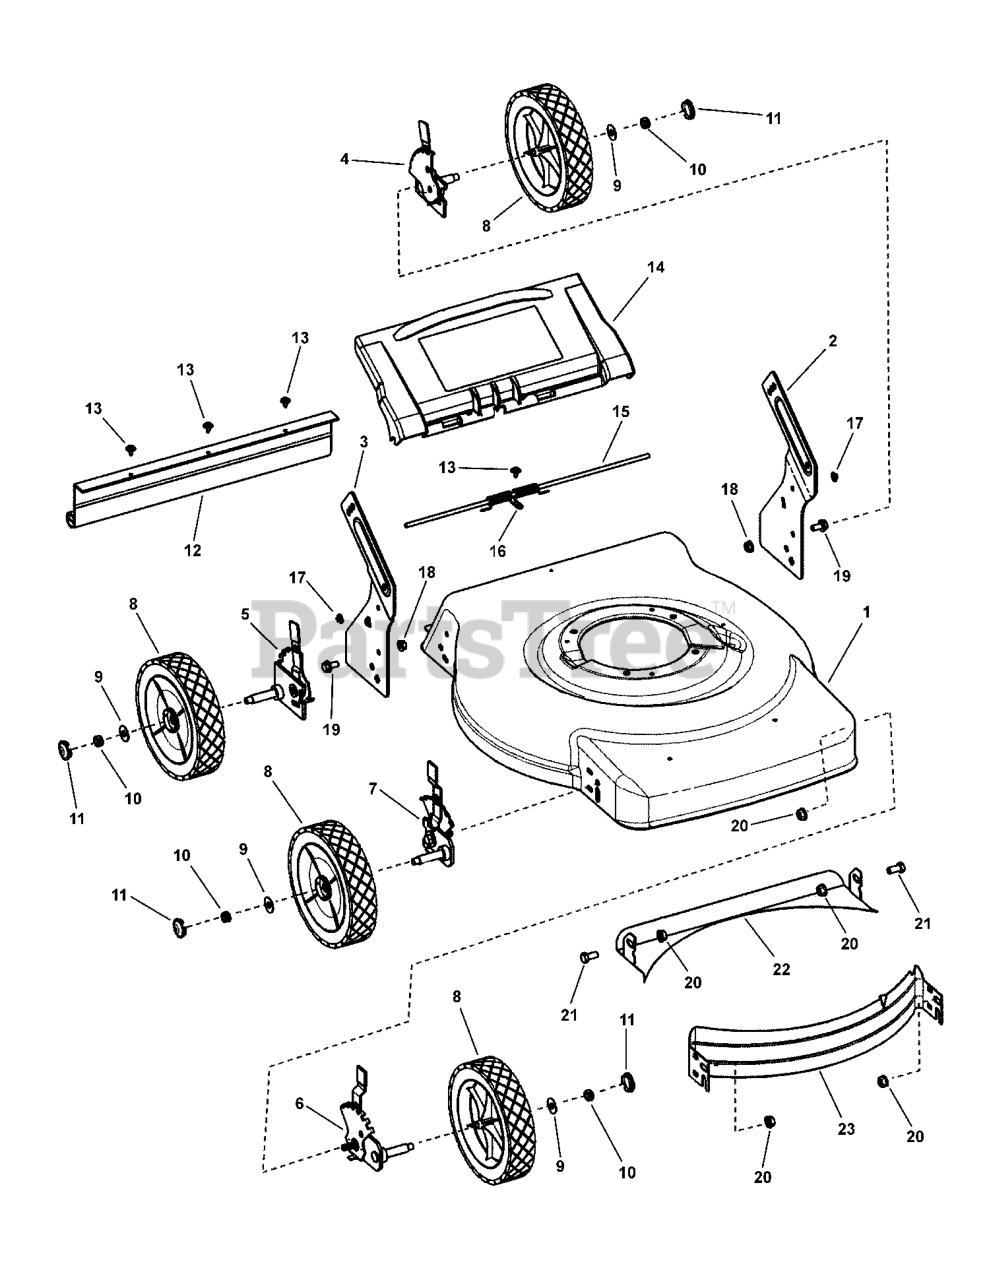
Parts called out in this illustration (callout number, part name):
1	DECK, 22 Walk-Behind
2	BRACKET, Lower Handle, 22 WBM, LH
3	BRACKET, Lower Handle, 22 WBM, RH
4	ASSEMBLY, Height-of-Cut, Right Rear
5	ASSEMBLY, Height-of-Cut, Left Rear
6	ASSEMBLY, Height-of-Cut, Left Front
7	ASSEMBLY, Height-of-Cut, Right Front
8	WHEEL, 8 x 2 Diamond-Pewter
9	WASHER, .382 ID x 1" OD x .031 Flat
10	NUT, 3/8-16 Hex Center Lock, YZ
11	HUBCAP, P290-Black
12	GUARD, Rear, 22 Deck Mower
13	SCREW, #10-24 x 1/2" Hex Washer Self-Tap (Sems)
14	DOOR, Rear, 22"
15	ROD, Pivot, Rear Door
16	SPRING, Torsion, Rear Door, 22 Walk
17	PUSHNUT, 1/4"
18	NUT, 5/16-18 Large Flange Center Lock
19	BOLT, 5/16-18 Hex Flange Lock
20	NUT, 3/8-16 Hex Flange Lock, GR 5
21	SCREW, 3/8-16 x 3/4", Hex Head Cap, GR 5
22	BAFFLE, Rear, 22" Deck
23	BAFFLE, Front, 22" WBM
